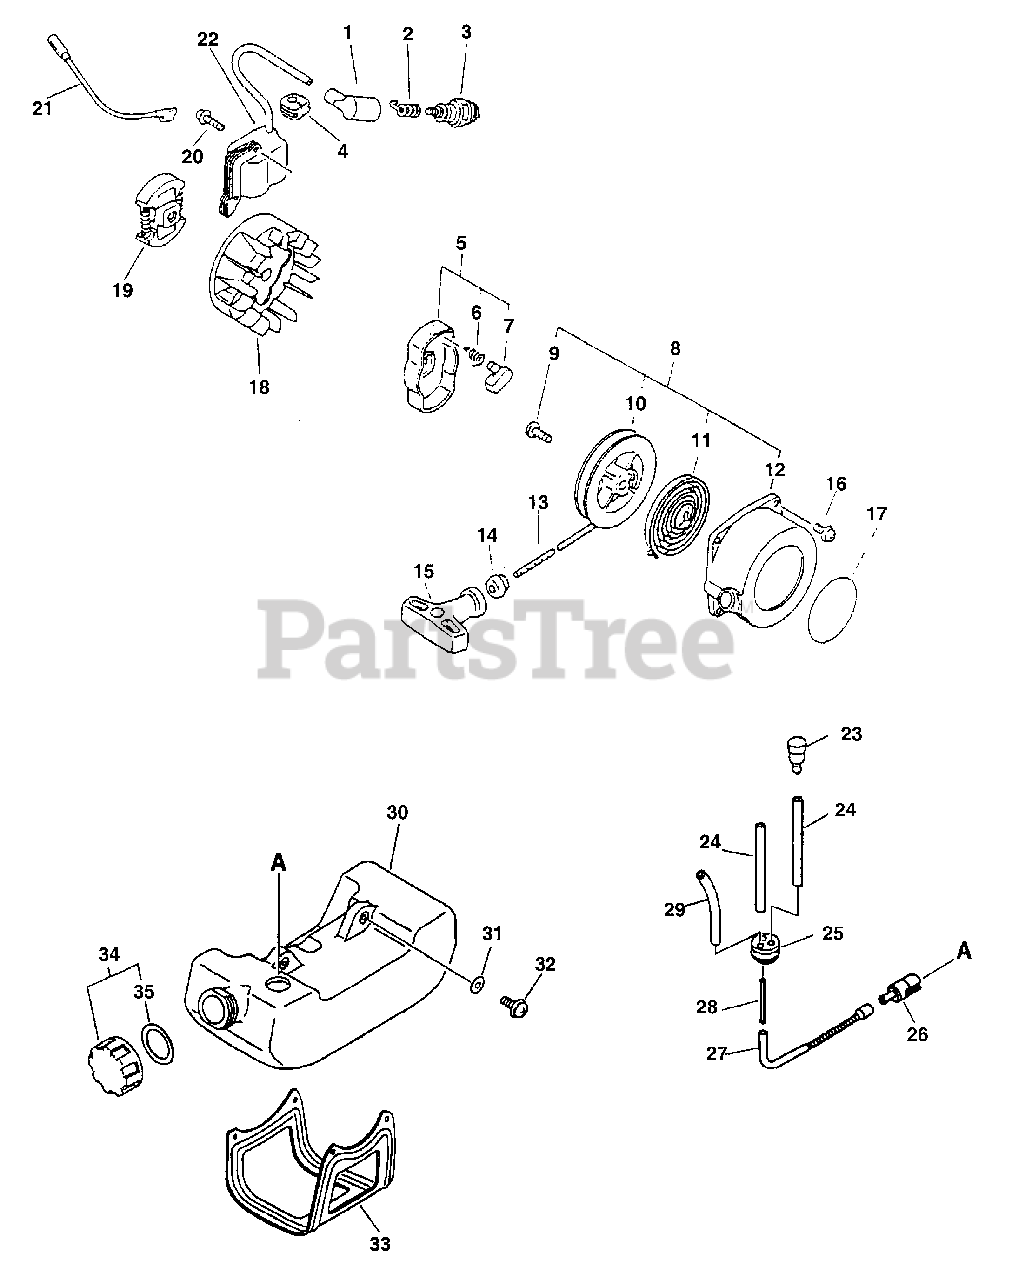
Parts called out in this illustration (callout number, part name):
1	CAP, SPARK PLUG
2	TERMINAL, SPARK PLUG CAP
3	SPARK PLUG -- BPM-7Y
3	SPARK PLUG -- RCJ-7Y
5	STARTER PAWL ASSY
6	SPRING, RETURN
7	PAWL, STARTER - BLACK
8	STARTER ASSY
10	REEL, ROPE
11	SPRING, REWIND
12	CASE, STARTER
13	ROPE, STARTER - 3X890
14	GUIDE, ROPE
15	GRIP, STARTER
16	SCREW - 4X16
17	LABEL - ECHO
18	FLYWHEEL
19	CLUTCH ASSY
20	SCREW - 4X22
21	LEAD - IGNITION
22	COIL, IGNITION
23	VENT, FUEL TANK
24	PIPE - 3X5X70 -- BLACK
25	GROMMET
26	FILTER, FUEL
27	PIPE, FUEL - CORRUGATED
28	CONNECTOR, PIPE
29	PIPE - 3X6X90 -- CLEAR
30	FUEL TANK ASSY
31	WASHER - 5
32	SCREW - 5X16
33	GUARD, FUEL TANK
34	CAP ASSY
35	GASKET, CAP
